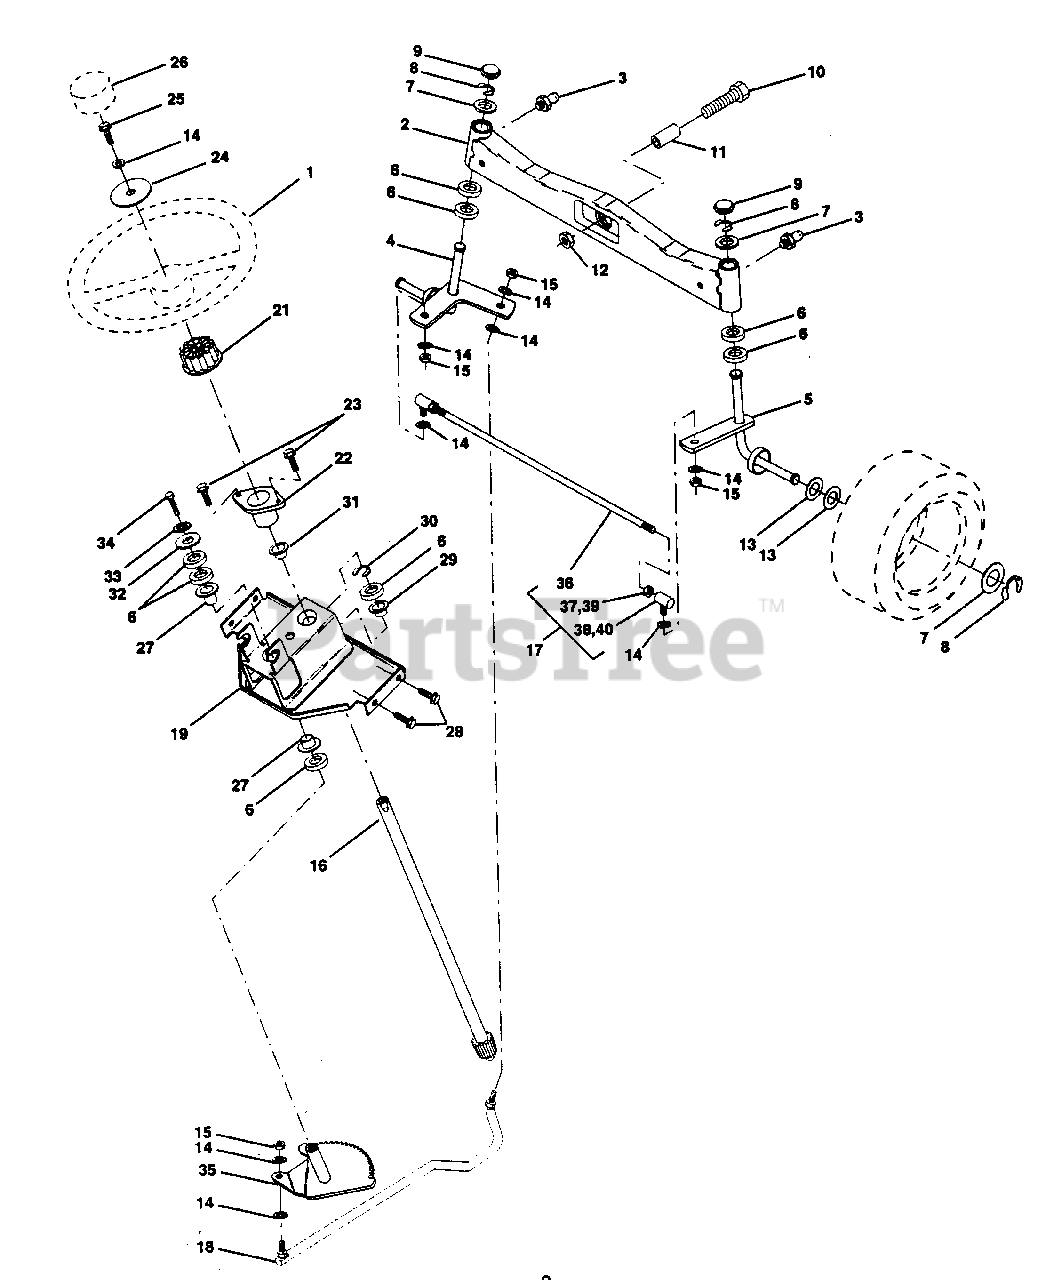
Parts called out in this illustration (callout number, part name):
1	Wheel, Steering
2	Axle Asm., Front
3	Fitting, Grease
4	Spindle Asm, LH
5	Spindle Asm., RH
6	Bearing, Race Thrust Harden
7	Washer 25/32 x 1-5/8 x 16 Ga.
8	Ring, Klip #T5304-75
10	Bolt, Fin Hex 5/8-11 x 2-3/4
11	Spacer, Brg. Axle Front
12	Nut, Lock Flange 5/8-11 Unc
13	Washer 25/32 x 1-1/4 x 16 Ga.
14	Washer, Lock Hvy Hlcl Spr 3/8
15	Nut, Fin Hex 3/8-24 Unf
16	Shaft Asm., Steering
17	Rod Asm., Tie Ball J Ball Vgt (Inc. Key No. 36-40)
18	Draglink, Ball Joint Solid Vgt
19	Support Asm., Steering Vgt
21	Adapter, Wheel Steering
22	Bushing, Strg. Blk
23	Screw, Slftp #10-16 x 1/2 Ty-b
24	Washer 13/32 x 2-3/8 x 8 Ga.
25	Bolt, Fin Hex 3/8-16 x 1 Gr. 5
26	Cap, Wheel Steering
27	Bearing, Col. Strg.
28	Screw Thdrol. 3/8-16 x 3/4 TY-TT
29	Bearing, Flange
30	Ring, Klip Truarc #5304-75
31	Bushing, Nyliner Snap
32	Washer 11/32 x 1 x 10 Ga.
33	Washer, Lock Hvy Hlcl Spr 5/16
34	Bolt, Hex Hd 5/16-18 x 3/4
35	Gear, Sector Steering
36	Tie Rod
37	Jam Nut RH Thread
38	Joint Asm. Ball RH Thread
39	Jam Nut LH Thread
40	Joint Asm. Ball LH Thread
